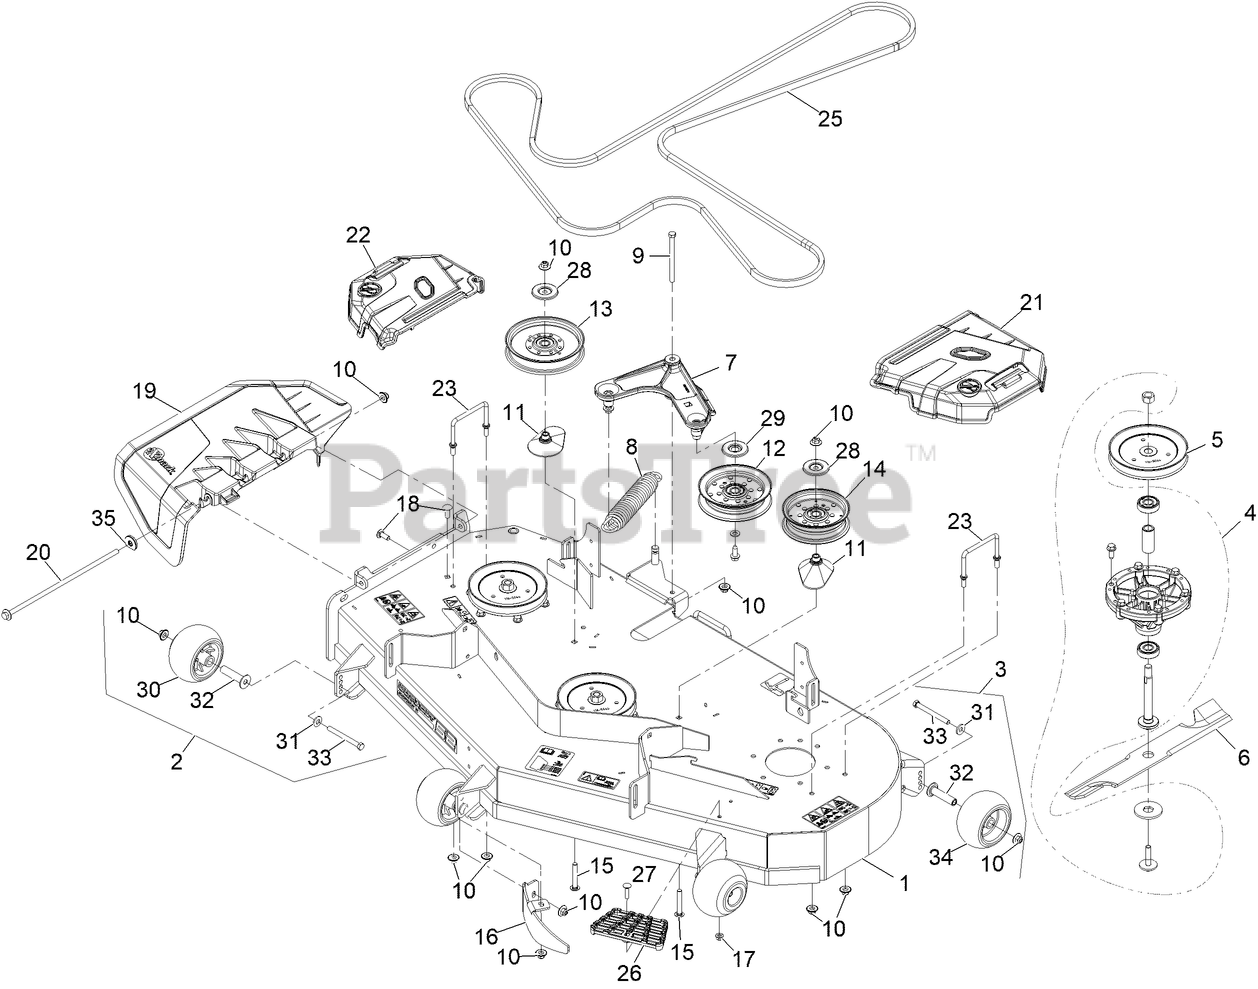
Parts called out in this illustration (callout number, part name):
1	ASM-DECK W/DECALS 523
2	KIT, ANTI-SCALP ROLLER
3	KIT-ANTISCALP ROLLER
4	ASM, CUTTER HOUSING COMPLETE
5	SHEAVE,BLADE DRIVE 6.50
7	ASM-IDLER ARM W/BEARINGS
8	SPRING-EXTENSION
9	SCREW-HH
10	Nut-Nyloc 3/8-16 Flg
11	SPACER-PULLEY
12	IDLER-PULLEY, FLAT
13	IDLER-PULLEY, FLAT 6.00X1.00
14	IDLER-PULLEY, FLAT 5.00X1
15	SCREW-CARR
16	BAFFLE-DOGLEG, LZE-PNS-52
17	NUT-HF, NI
18	SCREW-CARR
19	Chute-Deck Discharge
20	Pin, Chute
21	SHIELD, LT
22	SHIELD, RT
23	WIREFORM-COVER
26	STEP-DECK
27	Bolt-Carriage 5/16-18 X 1 1/4
28	SHIELD-DUST
29	SHIELD-GUARD, DUST
30	ROLLER-SCALP, ANTI
31	WASHER-BELLEVILLE
32	AXLE, ROLLER
33	SCREW-HH 3/8-16 X 3 3/4 GR 8
34	ROLLER-SCALP, ANTI
35	Retainer, Chute
